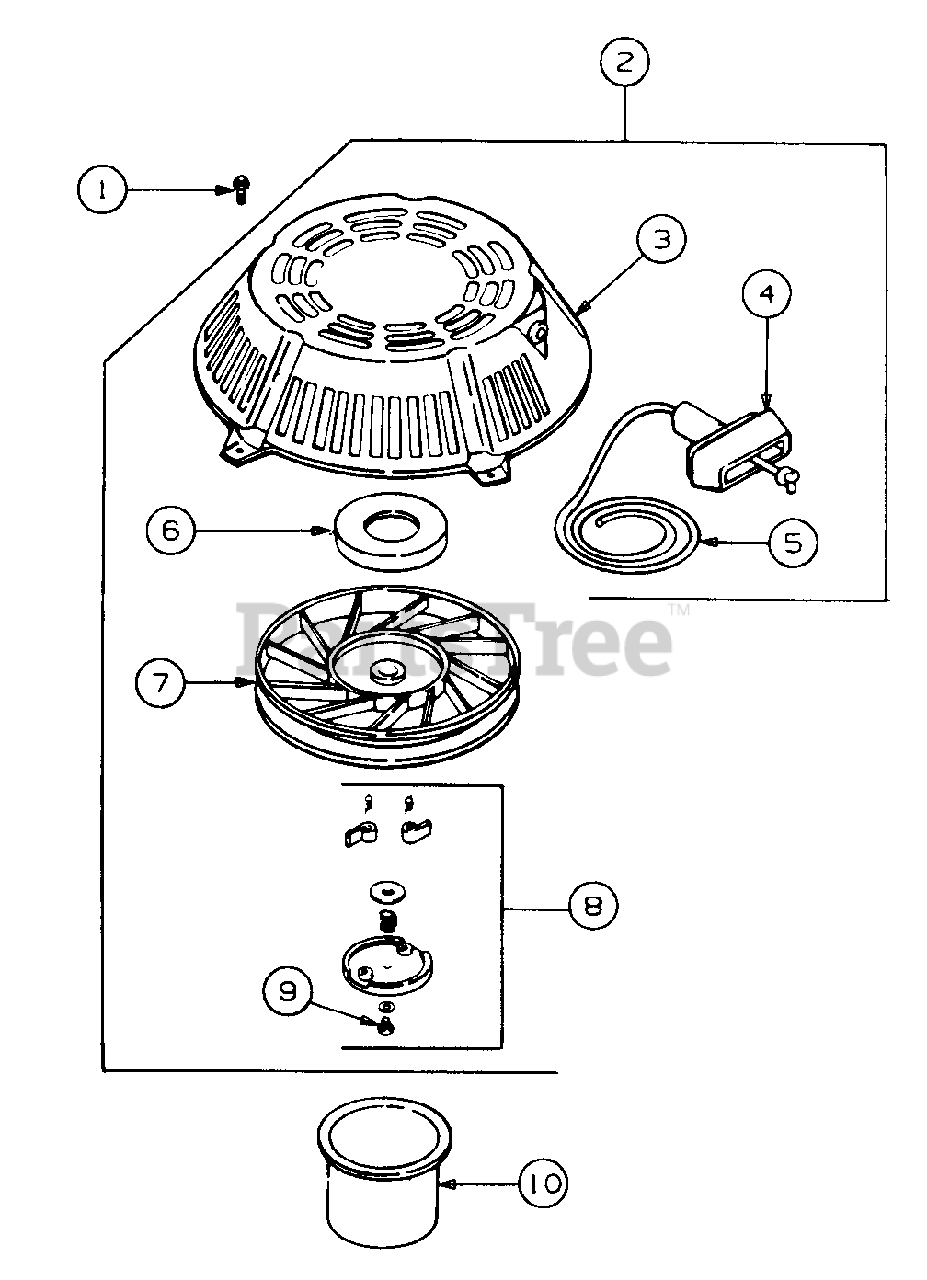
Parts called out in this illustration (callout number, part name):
1	Screw, M5 X 0.8 X 10
2	Starter, Retractable Assy (Includes Ref No. 3 thru 9)
3	Housing, Starter
4	Handle, Reocil Start
5	Rope, Starter
6	Spring & Keeper
8	Kit, PNawl (Dog) (Includes
9	Screw, Pozidriv
